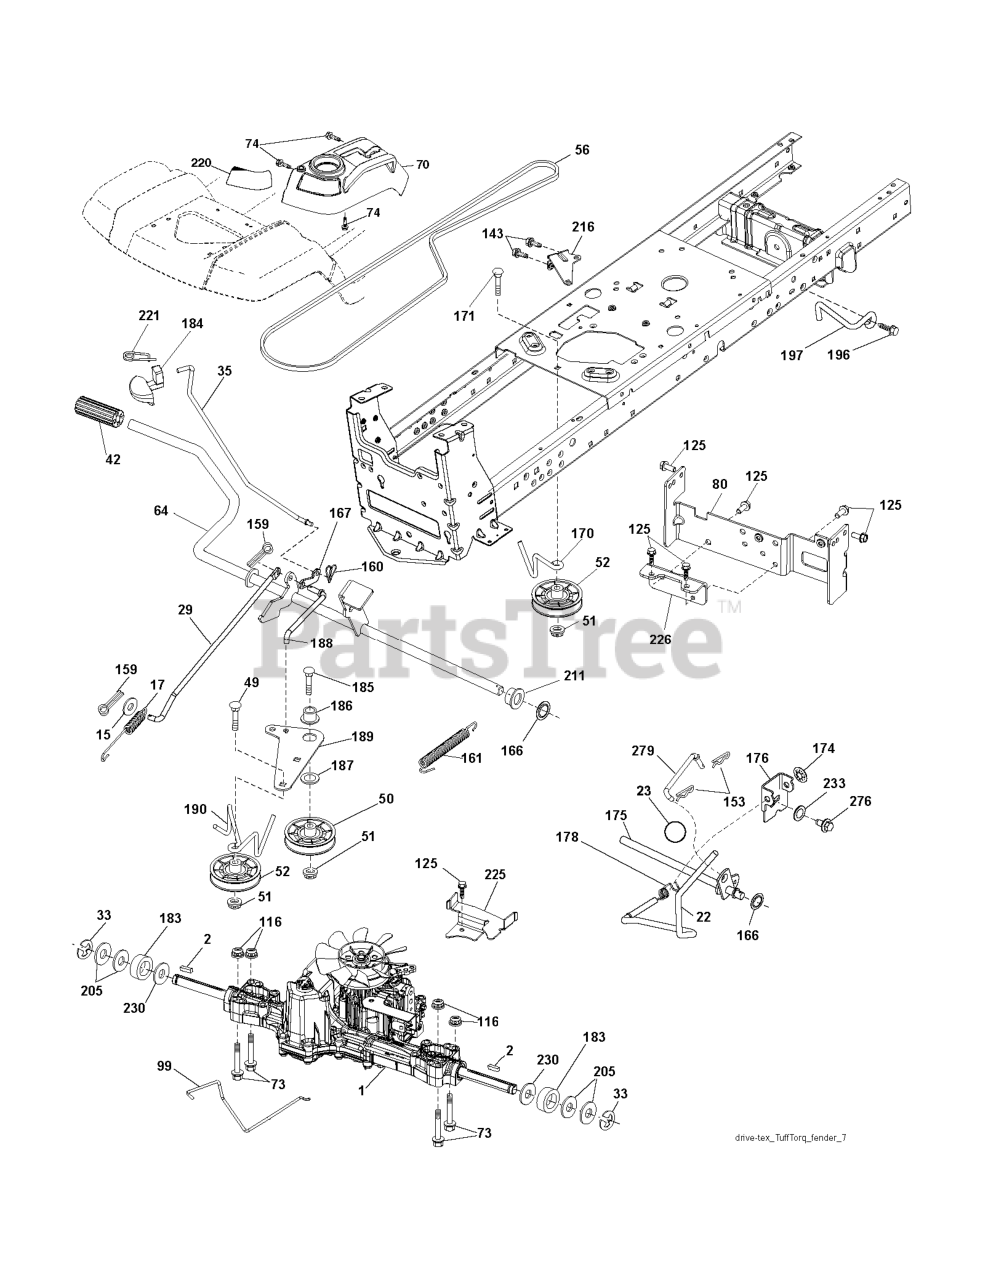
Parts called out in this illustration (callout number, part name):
2	SQUARE KEY
15	WASHER
17	SPRING.BRAKE.K46.GREEN
22	ROD.SHIFT.FENDER.STGT.
23	KNOB.DUCKHEAD.1/2
29	ROD.BRAKE.K46
35	ROD.BRAKE.PARKING.GT.H
42	PEDAL COVER T
50	IDLER.FLAT.910.OFFSET
51	NUT LOCK FLG 3/8-16 UNC
52	IDLER.V-GROOVE.910.OFFSET
56	V-BELT.MOWER.92.40.42/K46
64	SHAFT.ASM.PEDAL.BRAKE.
70	RP CONSOLE.ASM.HYDO.HUSQ.
73	BOLT HEX 5/16-18 GR 5
74	SCREW.HI-LO.CONSOLE
80	STRAP TORQUE
99	ROD ASM BYPASS
116	NUT LOCK HEX FLANGE 5/16-18
125	SCREW
143	Screw 5/16-18 x 1/2 Hex, Self Tapping 5/16-18 x 1/2
153	RETAINER M
159	COTTER PIN
160	RETAINER CLIP
161	SPRING, RETURN LT
166	NUT.PUSH.625.2006
167	LATCH.BRAKE.SPRING
170	KEEPER.V-IDLER.CENTER.
174	NUT.PUSH.500.2006
175	SHAFT ASM SHIFT
176	ARM.CLEVIS.ROD.SHIFT
178	SPRING.SHIFT.GT2006
183	SPACER AXLE
184	HANDLE.PARKG.BRK.HUSQ X667
186	SPACER.RETAINER
187	WASHER 12/32X2X10GA
188	RP.LINK.CLUTCH.GROUND.DRIVE
189	BELLCRANK.GROUND.DRIVE.TEX.
190	KEEPER.BELLCRANK.DRIVE
196	SCREW 3/8-16X1
197	LINK.CLUTCH.ANIT-ROTAT
211	BUSHING.SHAFT.BRAKE.HAND
216	BRACKET.PULLEY.IDLER.W/TEX
220	REFLECTOR.RH.TEX GT
221	RETAINER.SPRING.CLIP.H
225	KEEPER.BELT.TRANSAXLE.K46
226	BRACKET.MOUNT.TORQUE.K46.TLT
230	WASHER.HARDENED
233	WASHER SERRATED
276	BOLT FIN HEX 7/16-14 X 1
279	LINK.SHIFT.T/A.K46.FEND.TX
